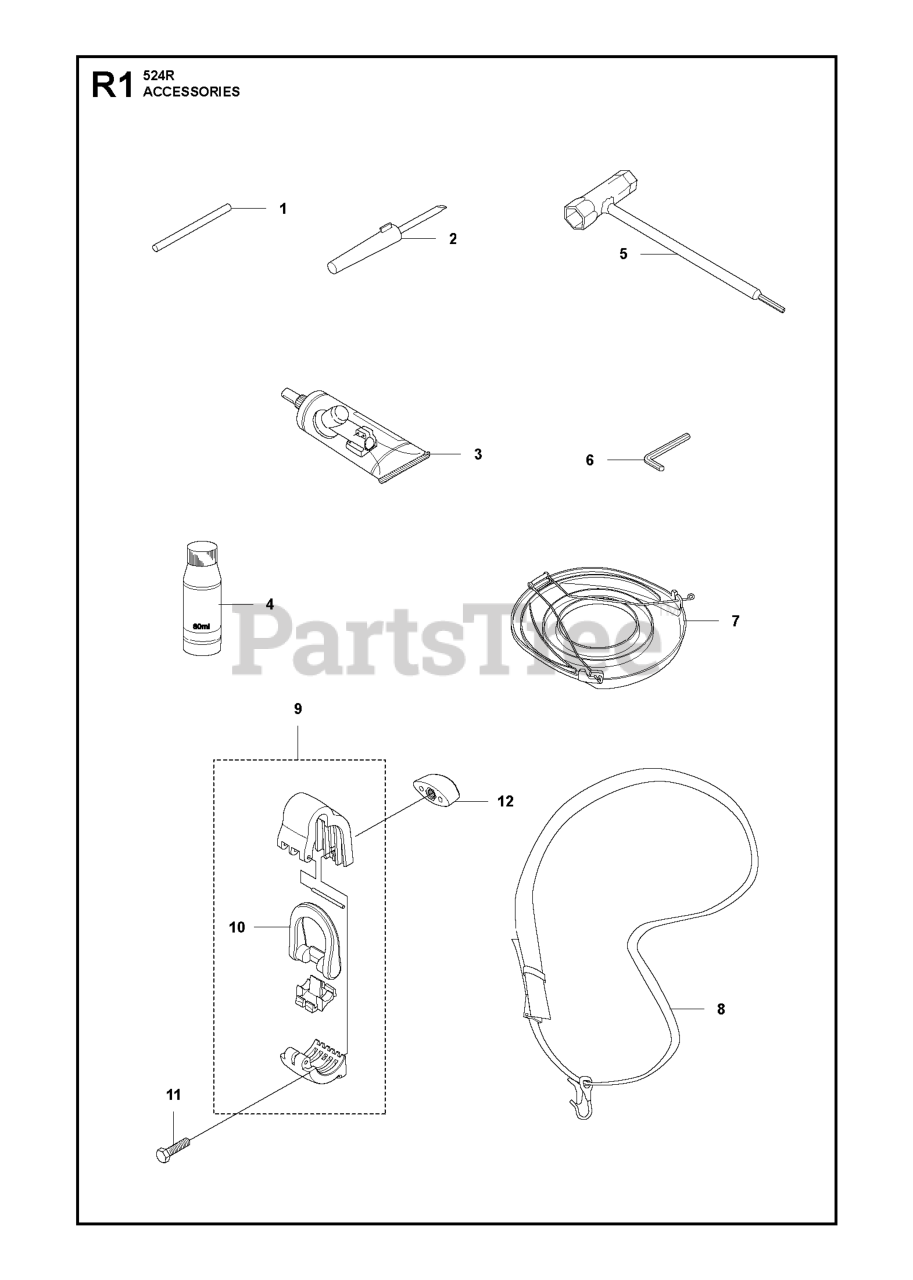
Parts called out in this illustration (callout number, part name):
1	LOCKING PIN
2	SCREWDRIVER
3	BEVEL GEAR GREASE
4	Four Stroke Engine Oil (SAE 10W-40) - 1 Bottle per Trimmer
5	RP COMBI TOOL
6	L-KEY WRENCH
7	BLADE GUARD TRANSPORT
8	Harness - Diagonal with sign
8	Harness-w/o warning
9	HANGING BRACKET
11	SCREW M6S 5X20
